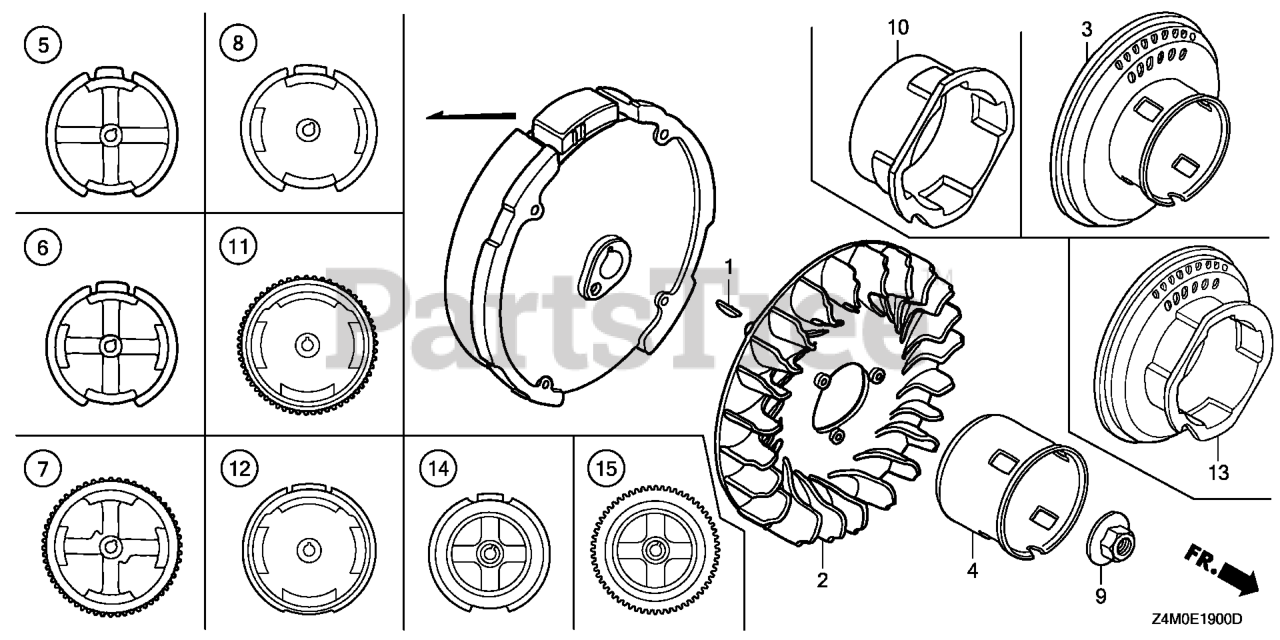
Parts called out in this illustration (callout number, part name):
1	KEY, SPECIAL WOODRUFF (25X18)
2	FAN, COOLING
9	NUT, SPECIAL (14MM)
13	PULLEY, STARTER
